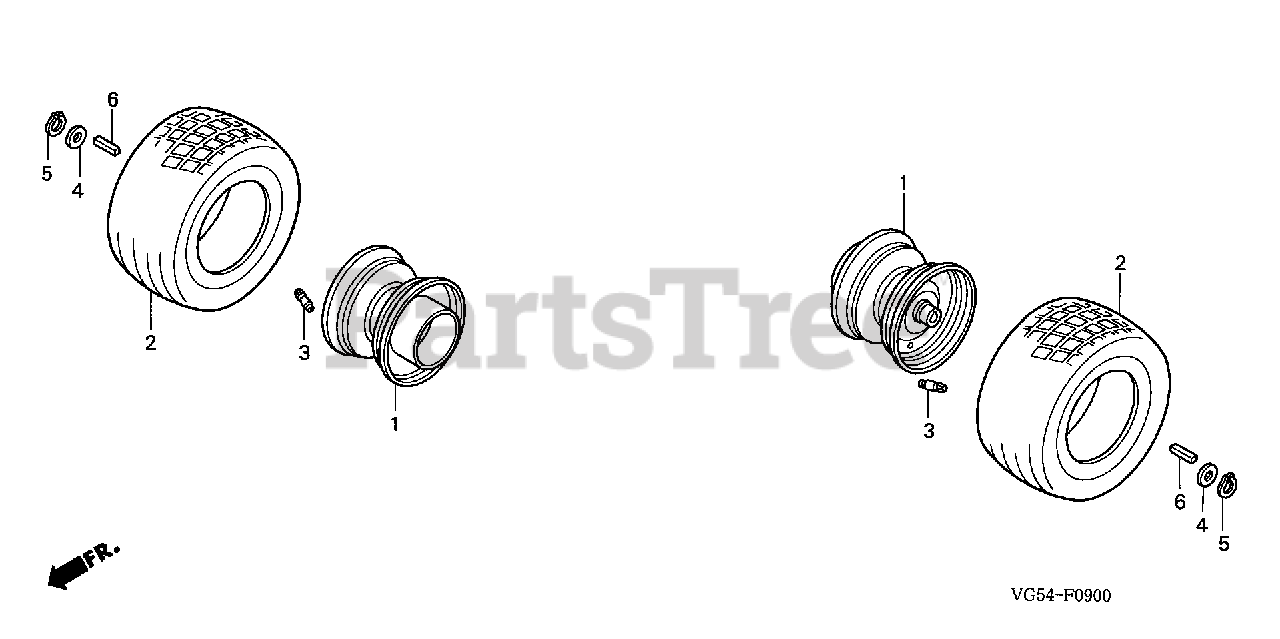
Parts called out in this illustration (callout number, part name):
1	WHEEL, RR.
3	VALVE (TR-412)
4	WASHER, SHIM (3/4"-1 1/4"X0.072")
5	CIRCLIP, EX. (3/4")
6	KEY (3/16"-2 1/2")
